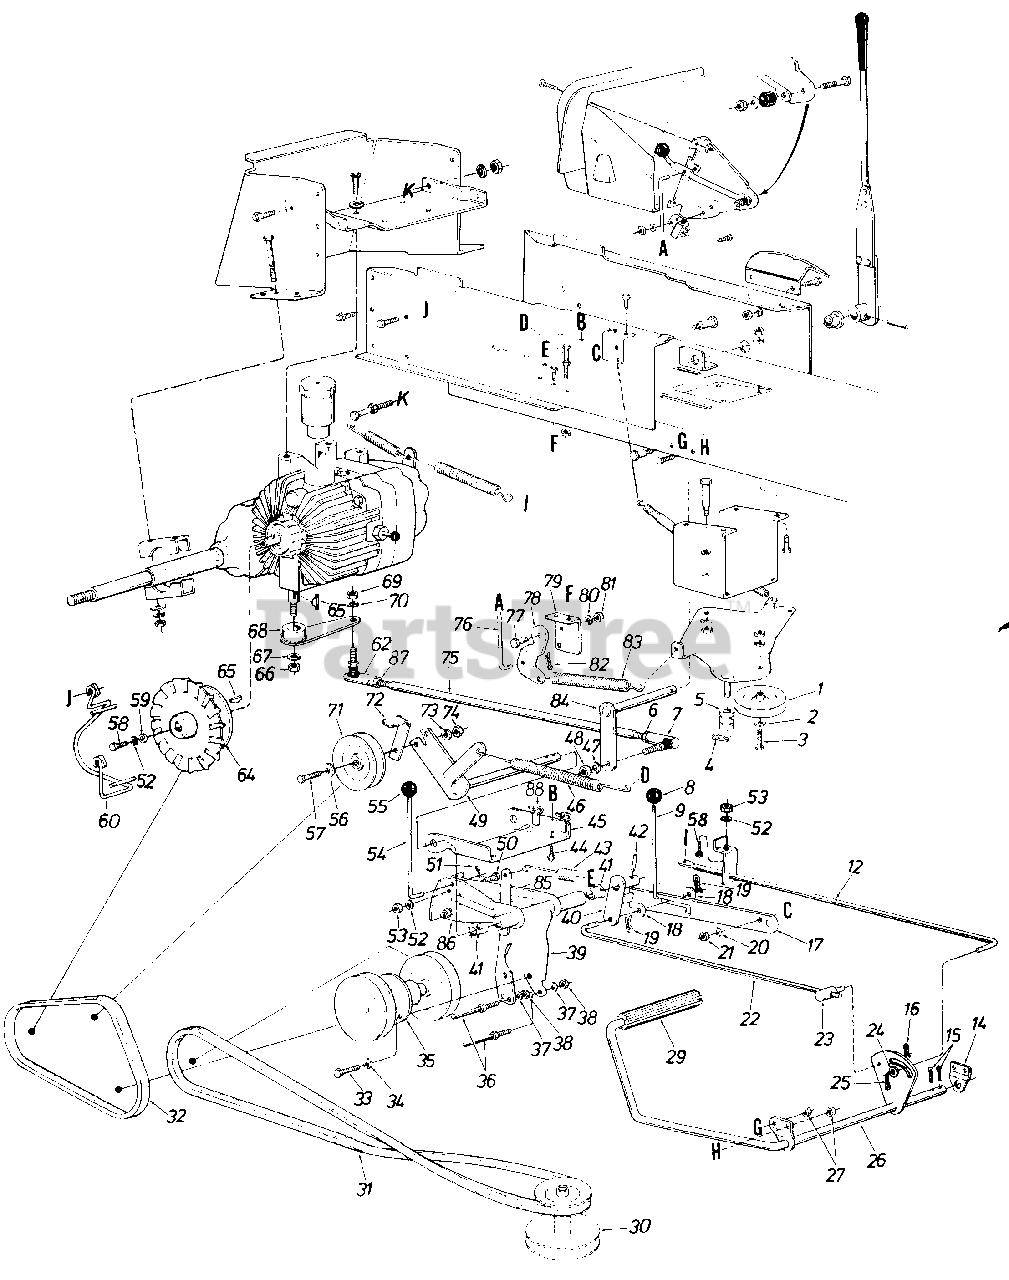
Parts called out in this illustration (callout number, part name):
1	4" Dia. "V"-Idler Pulley
2	Fl-Wash. 3/8" I.D.
3	Hex Bolt 3/8-16 x 1.25" Lg.
4	Intern. Cotter Pin 5/16" Dia.
5	Spacer
6	Hex Jam L-Nut 3/8-24 Thd.
7	Ball Joint Ass'y. 3/8-24 Thd.
8	Ball Knob
9	Parking Brake Link
12	Brake Rod
14	Clutch Rod Brg. Brkt.
15	Cotter Pin 1/8" Dia. x 1.00" Lg.
16	Hairpin Cotter 1/2" Dia.
17	Parking Brake Cam
18	Fl-Wash. .406 I.D. x 1.00" O.D. x .030
19	Hairpin Cotter 1/2" Dia.
20	L-Wash. 5/16" I.D.
21	Hex Nut 5/16-18 Thd.
22	Brake Cam Rod
23	Pivot Bushing
24	Fl-Wash. .401" I.D. x .749" O.D. x .057" Thk.
25	Cotter Pin 3132" Dia. x .75" Lg.
26	Clutch Brake Pedal Ass'y.
27	Hex L-Nut 3/8-16 Thd.
29	Foot Pad
30	Two-Step Engine Pulley 4.75" and 5.56"
31	"V"-Belt
32	"V"-Belt
33	Hex Sems Bolt 5/16-18 x .75" Lg.
34	L-Wash. 5/16" I.D.
35	Jack Shaft Ass'y.
36	Stud 3/8-16 x 3.62" Lg.
37	L-Wash. 3/8" I.D.
38	Hex Nut 3/8-16 Thd.
39	Jack Shaft Mtg. Brkt. Ass'y.
40	Clutch Idler Horn Ass'y.
41	Nyliner 518" I.D. x .88" Lg.
42	Spring Pin Spiral 1/4" Dia. x 1.5" Lg.
43	Ext. Spring
44	Hex Wash. Hd. Self-Tap Scr. 1/4-20 X .50" Lg.
45	Idler Mtg. Brkt.
46	Ext. Spring
47	L-Wash. 3/8" I.D.
48	Hex Nut 3/8-24 Thd.
49	Clutch Brkt. Ass'y.
50	Hex Bolt 1/4-20 x .50" Lg.
51	Internal Cotter Pin 5/16" Dia. Rod
52	L-Wash. 1/4" I.D.
53	Hex Nut 1/4-20 Thd.
54	Relief Valve Lockout Rod
55	Ball Knob
56	Fl-Wash. 3/8" I.D.
57	Hex Bolt 3/8-16 x 1.25" Lg.
58	Hex Bolt 1/4-20 x .62" Lg.
59	Fl-Washer
60	Belt Guard Ass'y.
62	Ball Joint Ass'y. 3/8-24 L.H. Thd.
64	Transaxle Pulley w/Fan
65	Hi-Pro Key 1/8" x 1/2" Dia.
66	Hex Nut 3/8-16 Thd.
67	L-Wash. 3/8" I.D.
68	Pintle Arm Ass'y.
69	Hex Nut 3/8-24 Thd.
70	L-Wash. 3/8" I.D.
71	4" "V"-Idler Pulley
74	Hex Nut 3/8-16 Thd.
75	Speed Control Rod
76	Deck Control Rod
77	Shld. Scr. .437" Dia. x .162" Lg. (5/16-18)
78	Deck Control Pivot Brkt.
79	Parking Brake Cam Mtg. Brkt.
80	L-Wash. 5/16" I.D.
81	Hex Nut 5/16-18 Thd.
82	Internal Cotter Pin 5/16" Rod
83	Extension Spring
84	Speed Control Shaft Ass'y.
85	Relief Valve Cam L.H.
86	Relief Valve Cam R.H.
87	Hex Jam L-Nut 3/8-24 L.H. Thd.
88	Plastic Hose Clamp
